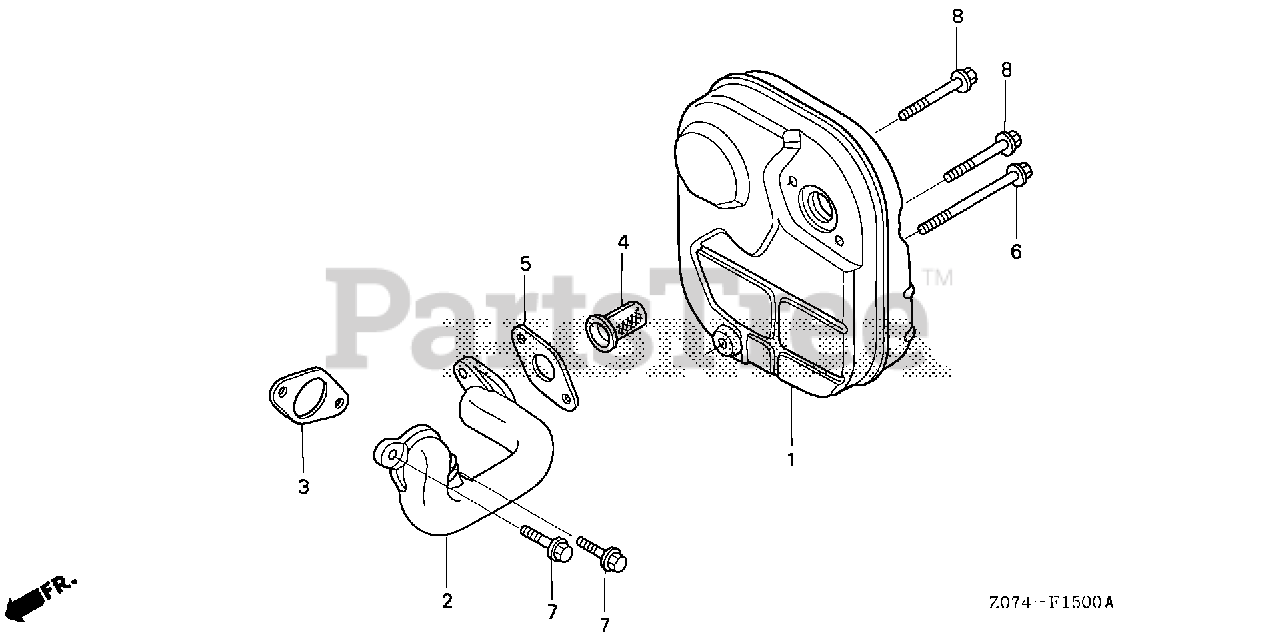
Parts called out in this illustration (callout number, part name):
1	MUFFLER
3	GASKET, EX. PIPE
4	ARRESTER KIT, SPARK
5	GASKET, MUFFLER
6	BOLT, FLANGE (6X65)
7	BOLT, FLANGE (6X23)
8	BOLT, FLANGE (6X45)
